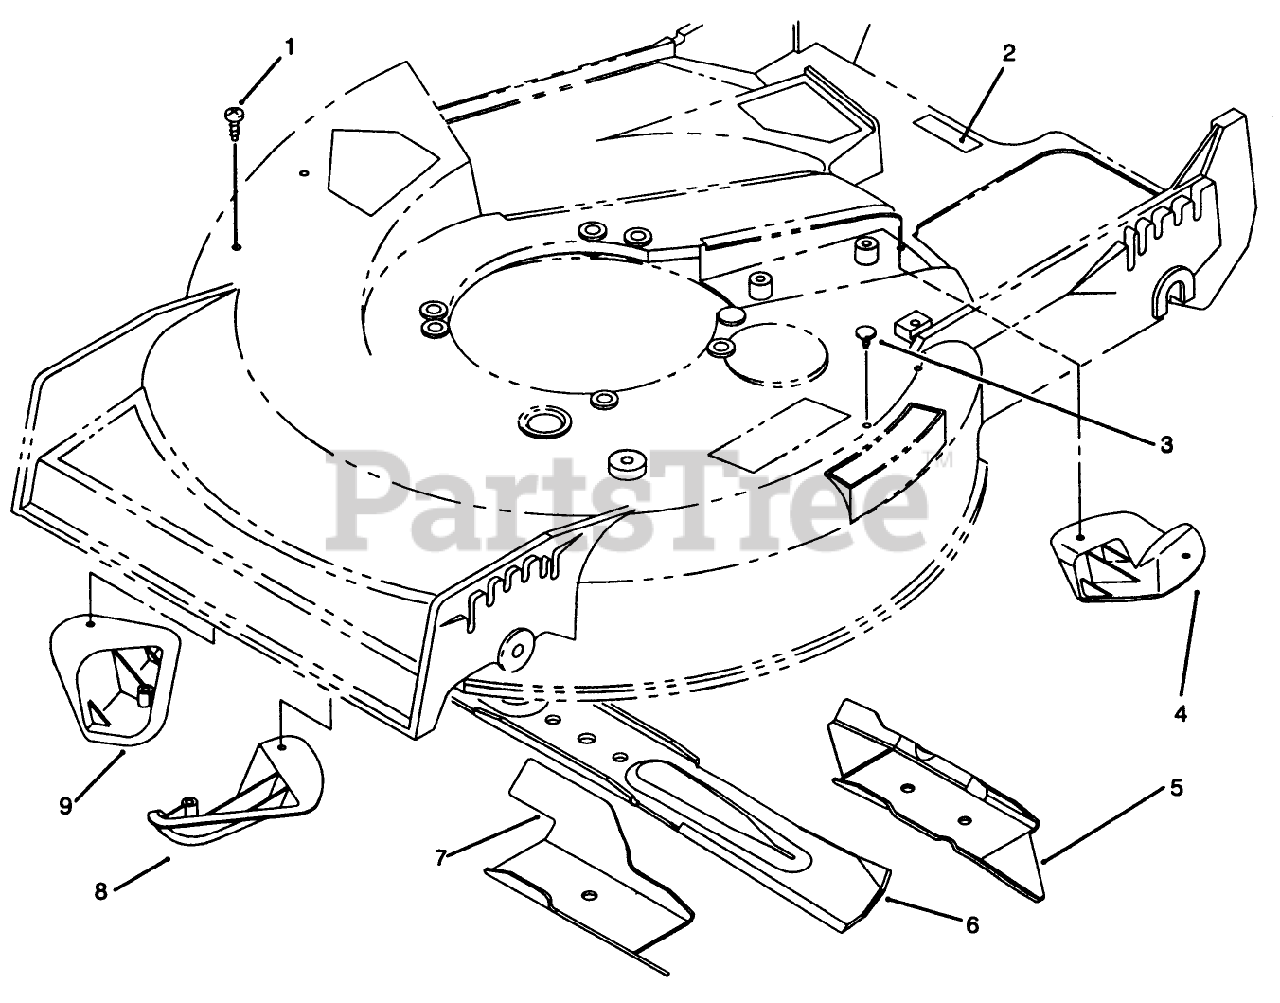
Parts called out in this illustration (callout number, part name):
1	SCREW-PPH
2	DECAL - CAUTION
3	PLUG - HOLE
4	KICKER-REAR
5	Accelerator
6	Blade
7	Accelerator
8	KICKER-RH
9	KICKER-FRONT
